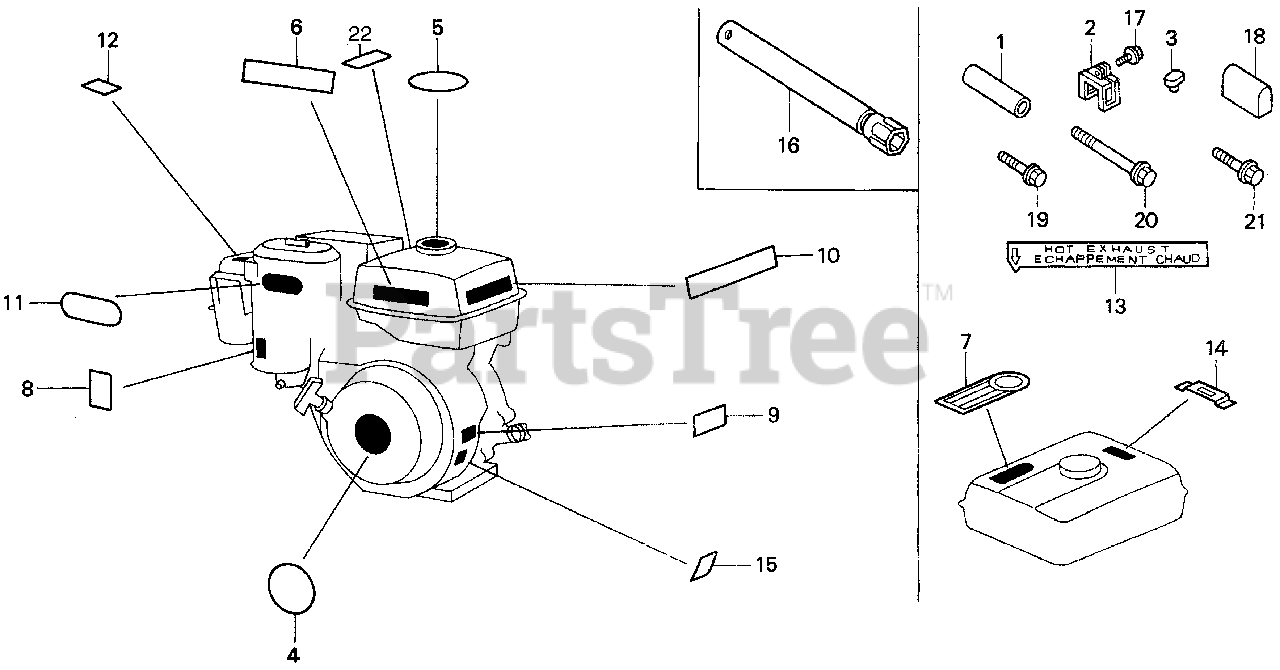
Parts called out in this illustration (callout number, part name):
4	EMBLEM
5	MARK, CAUTION (EXTERNAL)
6	LABEL, CAUTION
8	MARK, CHOKE (EXTERNAL)
9	LABEL, SPECIFICATION
10	MARK, OIL ALERT (GERMAN)
10	MARK, OIL ALERT (FRENCH)
10	MARK, OIL ALERT (E)
16	WRENCH, SPARK PLUG
22	LABEL, FUEL CAUTION
